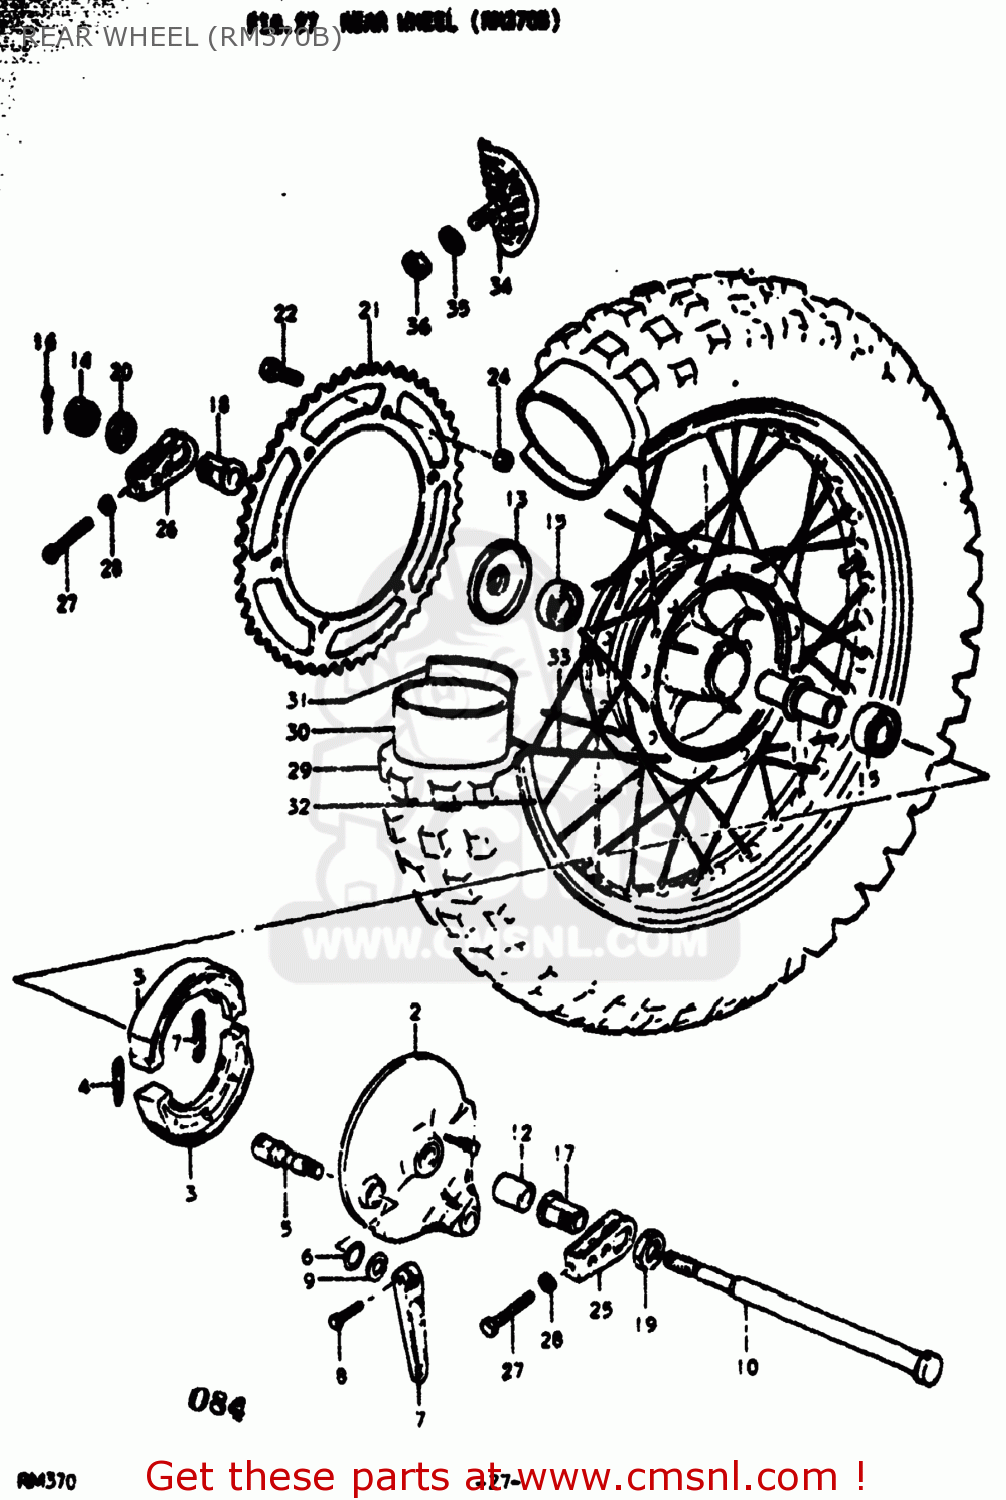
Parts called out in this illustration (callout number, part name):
1	HUB REAR
2	PANEL,REAR HUB
3	SHOE,BRAKE
4	SPRING
5	CAM,FRONT BRAKE
6	DUST SEAL
7	LEVER,FRONT BRAKE CAM
8	BOLT
9	WASHER (15X24X1.6)
10	AXLE,REAR
11	SPACER,REAR HUB BEARING
12	SPACER
13	SPACER,REAR AXLE
14	NUT
15	BEARING
16	PIN 30X40
17	SPACER,CHAIN ADJUSTER
18	SPACER,CHAIN ADJUSTER
19	NUT
20	NUT
21	SPROCKET,REAR
22	SCREW
24	NUT
25	ADJUSTER,CHAIN
26	ADJUSTER,CHAIN
27	BOLT
28	NUT
29	TIRE
30	TUBE ASSEMBLY,WHEEL,INNER
31	PROTECTOR,WHEEL,INNER
32	RIM,REAR WHEEL
33	SPOKE SET,REAR
34	STOPPER,BEAD
35	WASHER
36	NUT
